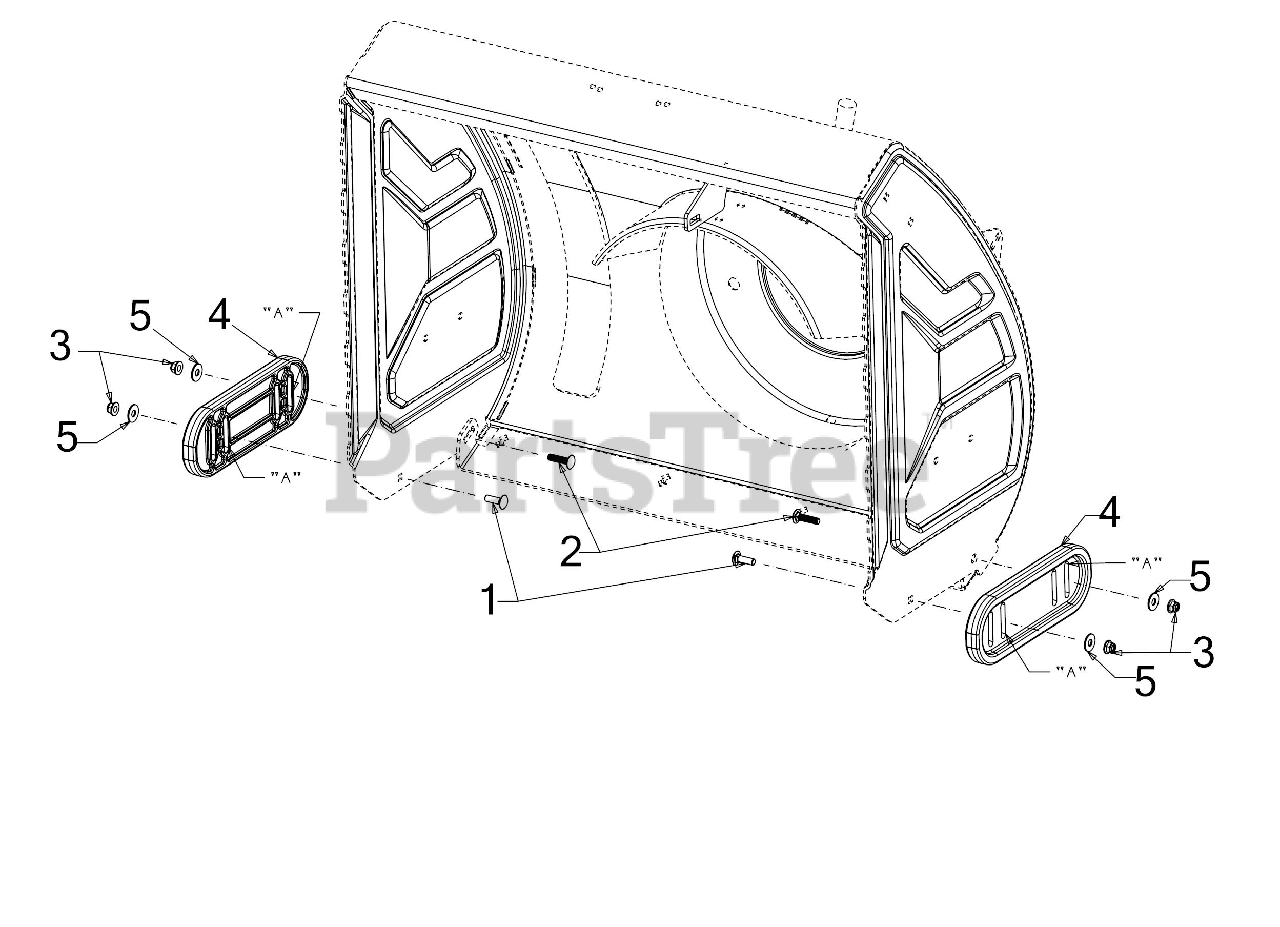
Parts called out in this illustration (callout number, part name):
1	CARRIAGE BOLT 5/16-18 x 1.00
2	CARRIAGE BOLT 5/16-18 X 1.25
3	FLANGE LOCK NUT 5/16-18
4	DELUXE SLIDE SHOE
5	FLAT WASHER
